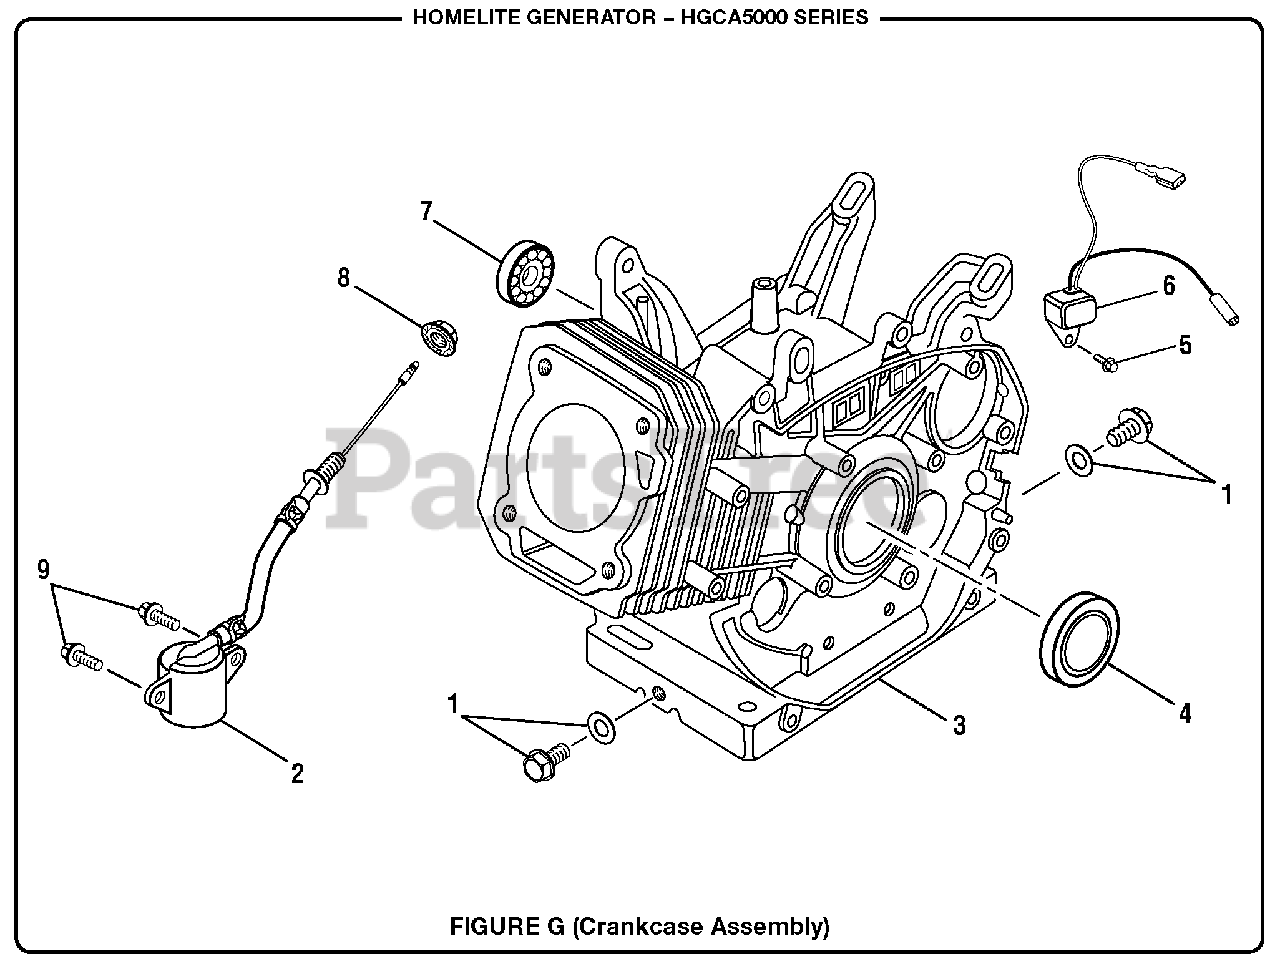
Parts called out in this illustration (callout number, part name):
1	Drain Plug Assembly
2	Oil Sensor Assembly
3	Short Block Cover Assembly w/Crankcase
4	Oil Seal (35 mm x 52 mm x 8 mm)
5	Bolt (M6 x 12 mm Flange Hd.)
7	Ball Bearing (6202)
8	Flange Nut (M10)
9	Bolt (M6 x 16 mm, Flange Hd.)
